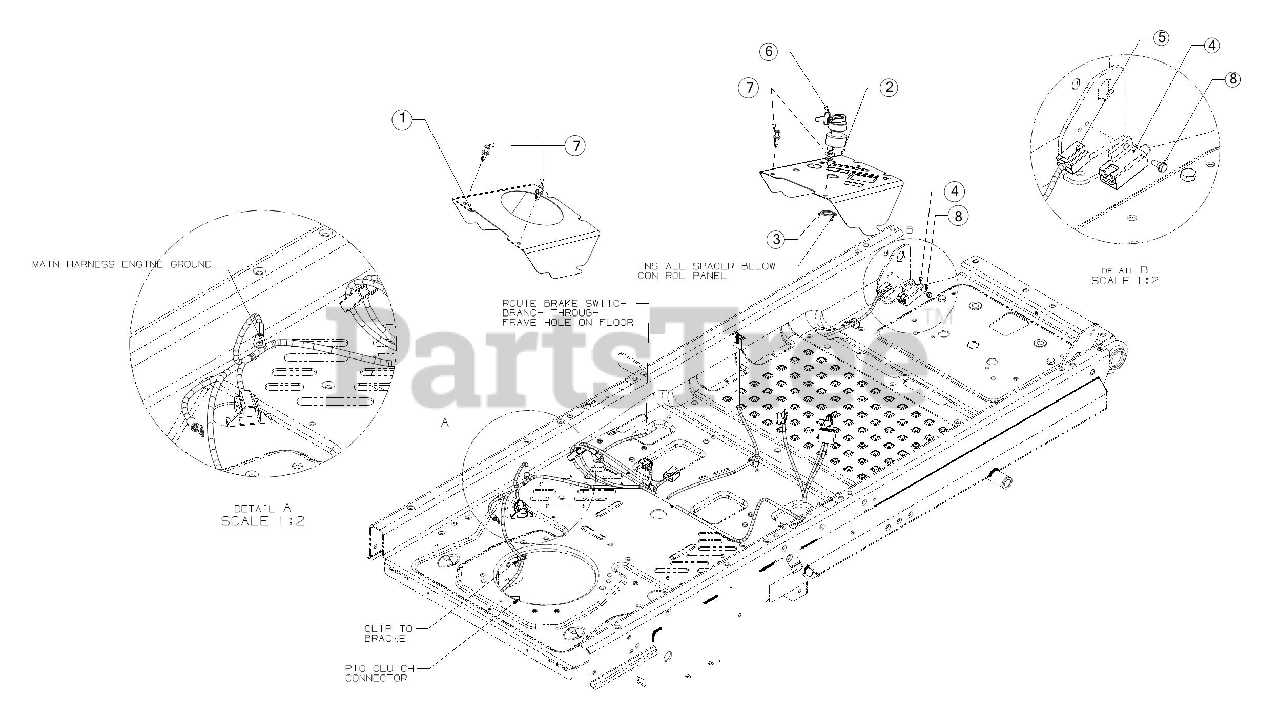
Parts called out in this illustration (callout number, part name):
4	INTERLOCK SWITCH (NO/NC)
6	IGNITION SWITCH
7	PLASTIC RIVET
8	SHOULDER SCREW
